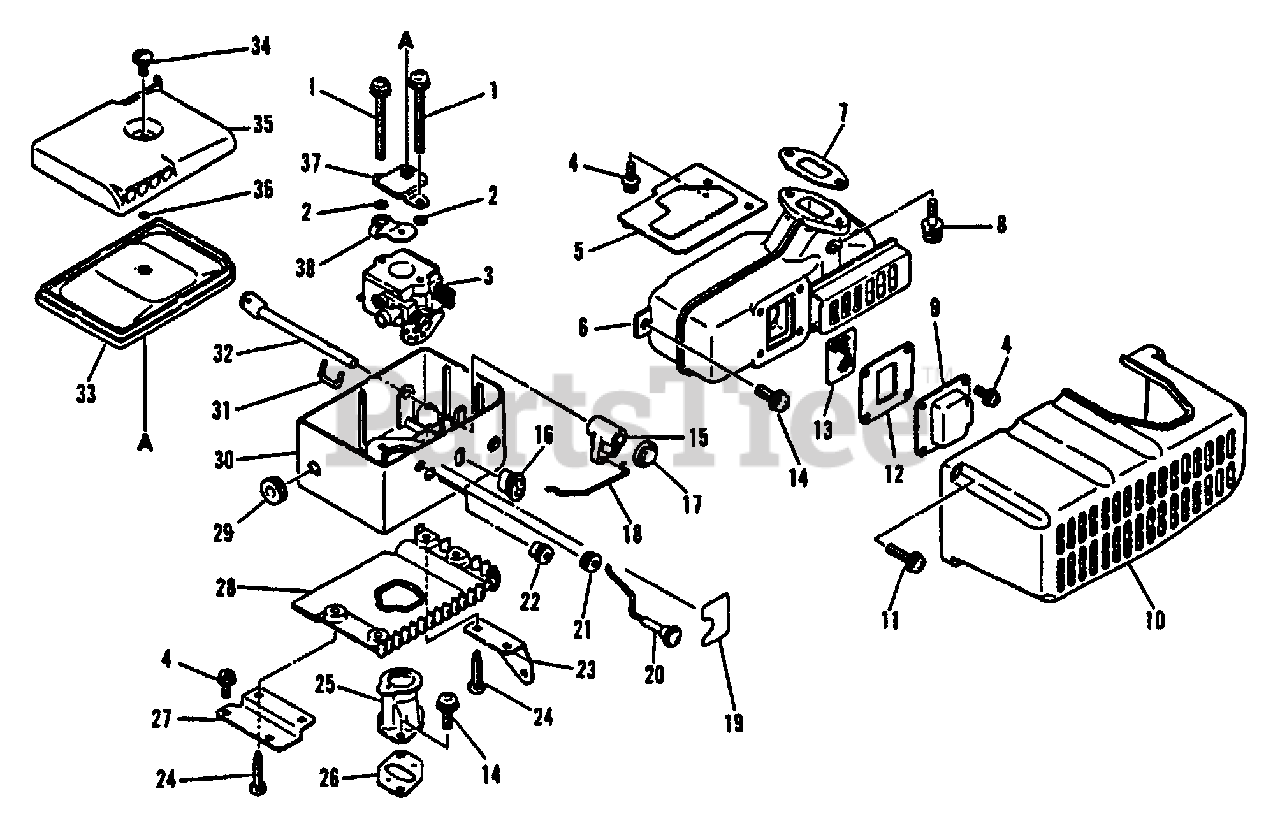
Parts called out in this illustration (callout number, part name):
1	SCREW - 5X40
2	WASHER - 5
3	CARBURETOR WA-157
4	SCREW - 4X10
5	INSULATOR
6	MUFFLER
7	GASKET, EXHAUST
8	SCREW - 5X16
9	GUIDE, EXHAUST
10	COVER, EXHAUST
11	SCREW - 5X20
12	GASKET, EXHAUST
13	SCREEN, SPARK ARRESTOR
14	SCREW - 5X14
15	ARM, THROTTLE LEVER
16	GROMMET
17	GUIDE, THROTTLE ROD
18	ROD, THROTTLE
19	LABEL
20	ROD, CHOKE
22	GROMMET
24	SCREW - 5X25
25	ADAPTOR, INTAKE
26	GASKET, INTAKE
28	INSULATOR
30	CASE, CARBURETOR
31	CONNECTOR, THROTTLE
32	SHAFT, THROTTLE
33	FILTER, AIR
34	THUMBSCREW
35	COVER, AIR FILTER
36	O-RING - 3
37	BRACKET, AIR CLEANER
38	SHUTTER, CHOKE
